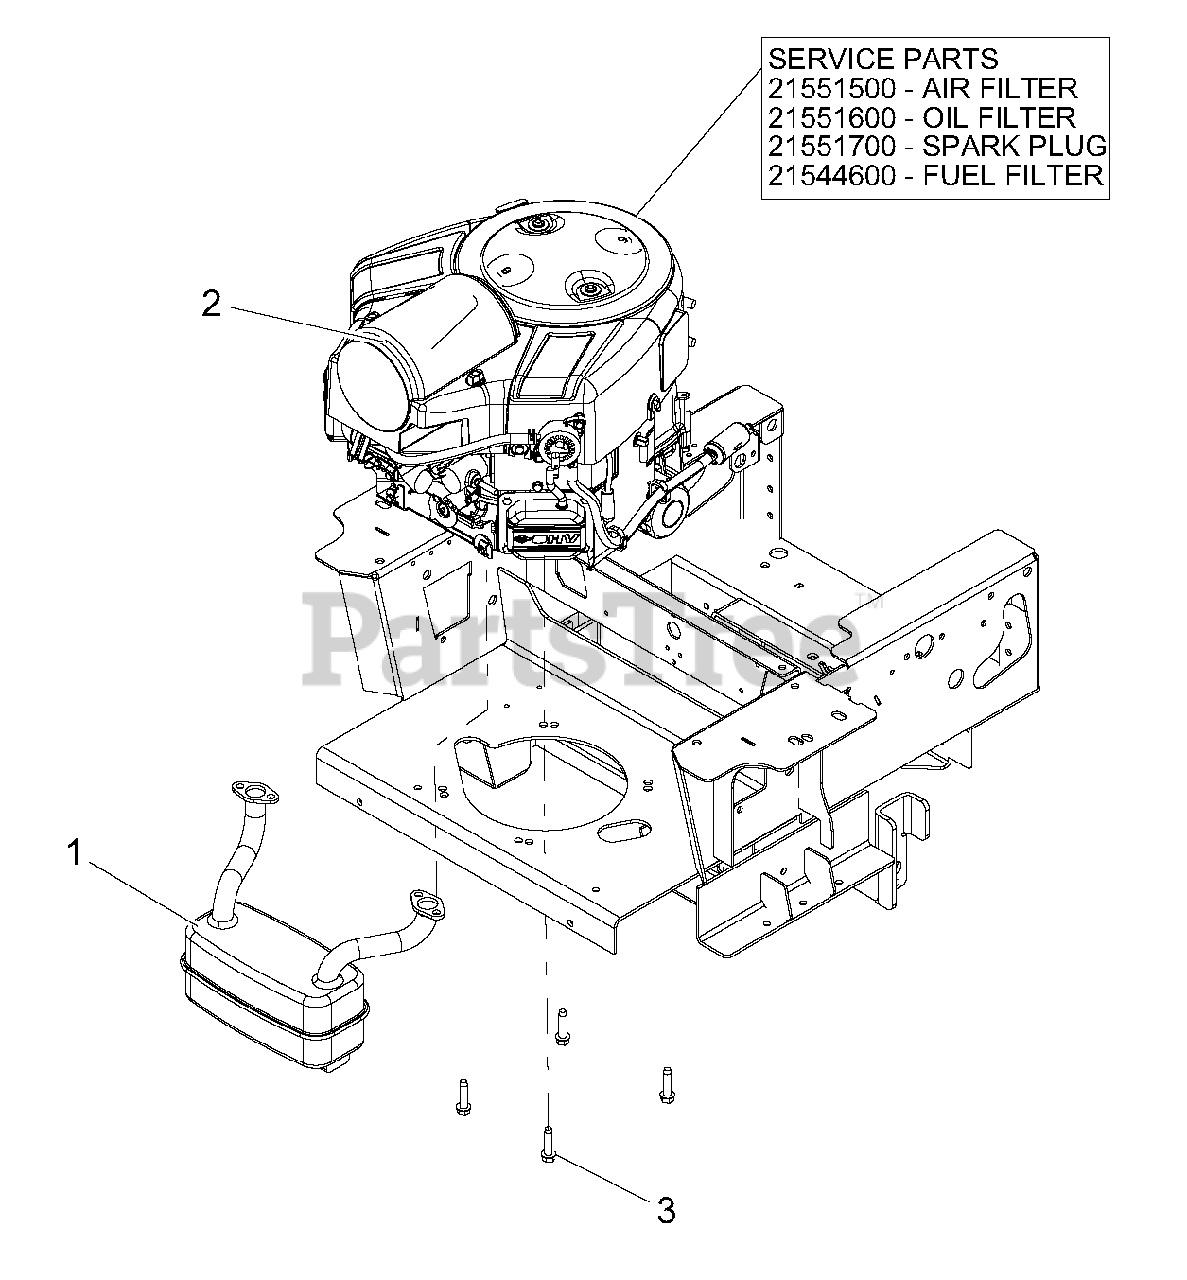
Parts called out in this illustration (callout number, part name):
1	ASM, MUFFLER
2	ENGINE, B&S 44Q9770199G5
3	SCR-TAP .38-16X1.50 HWH TR YZ
